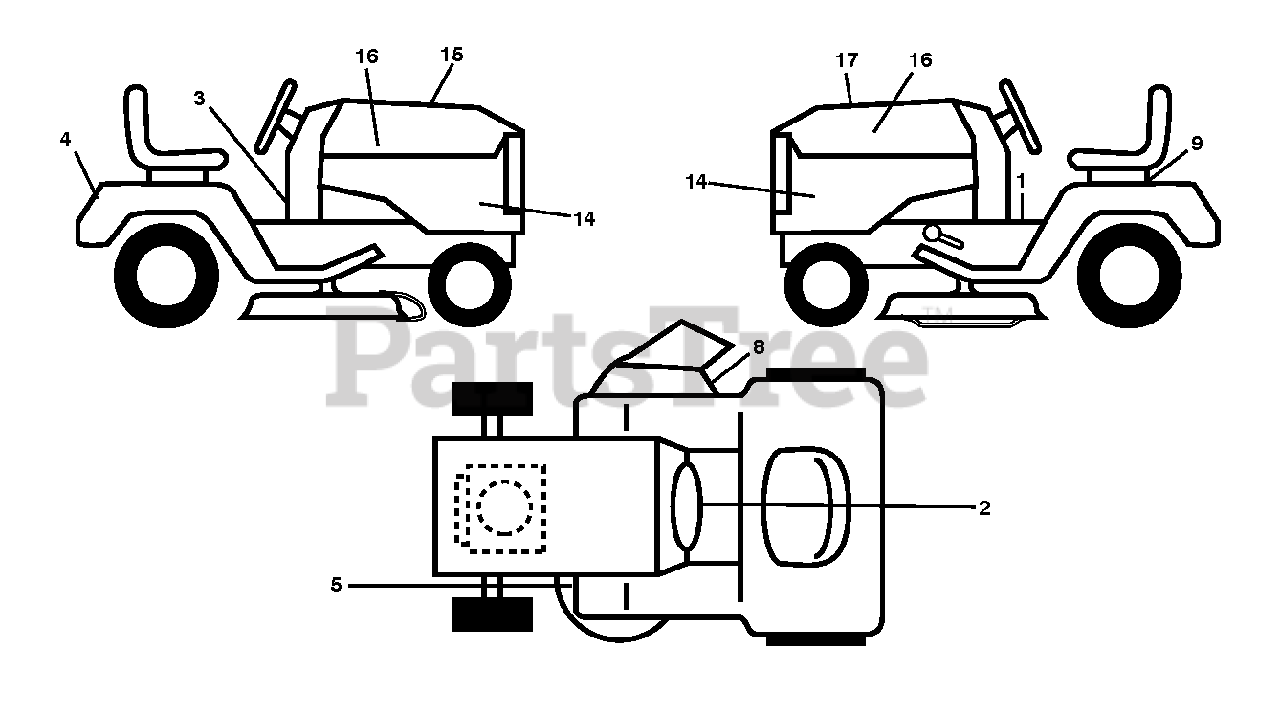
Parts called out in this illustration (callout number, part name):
1	DECAL.WARN.START.INSTRUCTIONS
2	LABEL.EMISS.CA.HUSQ/LOWES.2011
3	DECAL, WARNING SPARK ARRESTOR
4	DECAL.FENDER
5	DECAL.MOWER
8	DECAL.MOWER.SCH.48/54
9	DECAL BTRY SYMBOLS
14	DECAL.PNL.SD.LGT2554.KOHL.
15	DECAL.WARNING.CUST.RESP.E85.
16	RP.DECAL.BADGE.170MM.TEXTLOGO
18	DECAL.BYPASS.FENDER.CRD.LT.YT
19	PAD.FOOTREST.LH
20	PAD.FOOTREST.RH
